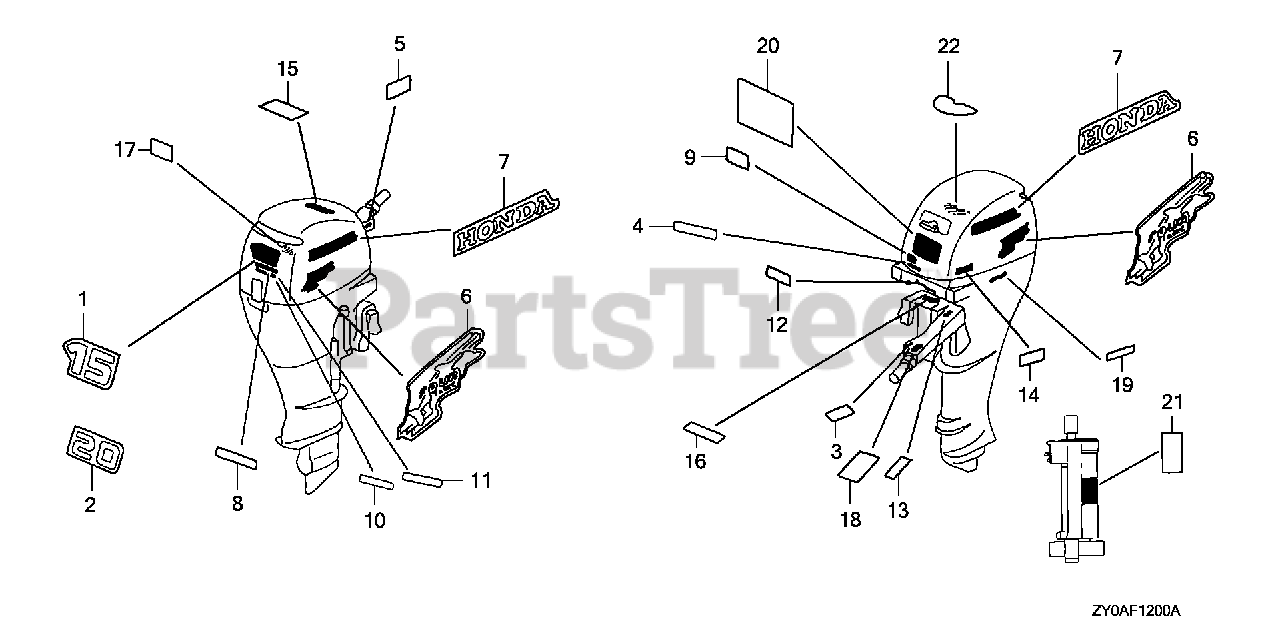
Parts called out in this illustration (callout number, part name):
1	MARK, RR. (15)
4	MARK, SPARE CLIP (ENGLISH)
6	MARK, SIDE
7	MARK, SIDE STRIPE (HONDA)
8	MARK, POWER THRUST
9	MARK (E-SPEC)
11	MARK, POWER TILT
17	LABEL, OIL CAUTION (ENGLISH)
19	LABEL, STORING CAUTION (ENGLISH)
20	LABEL, WARNING OPERATOR (ENGLISH)
22	MARK, EMERGENCY STARTER (ENGLISH)
